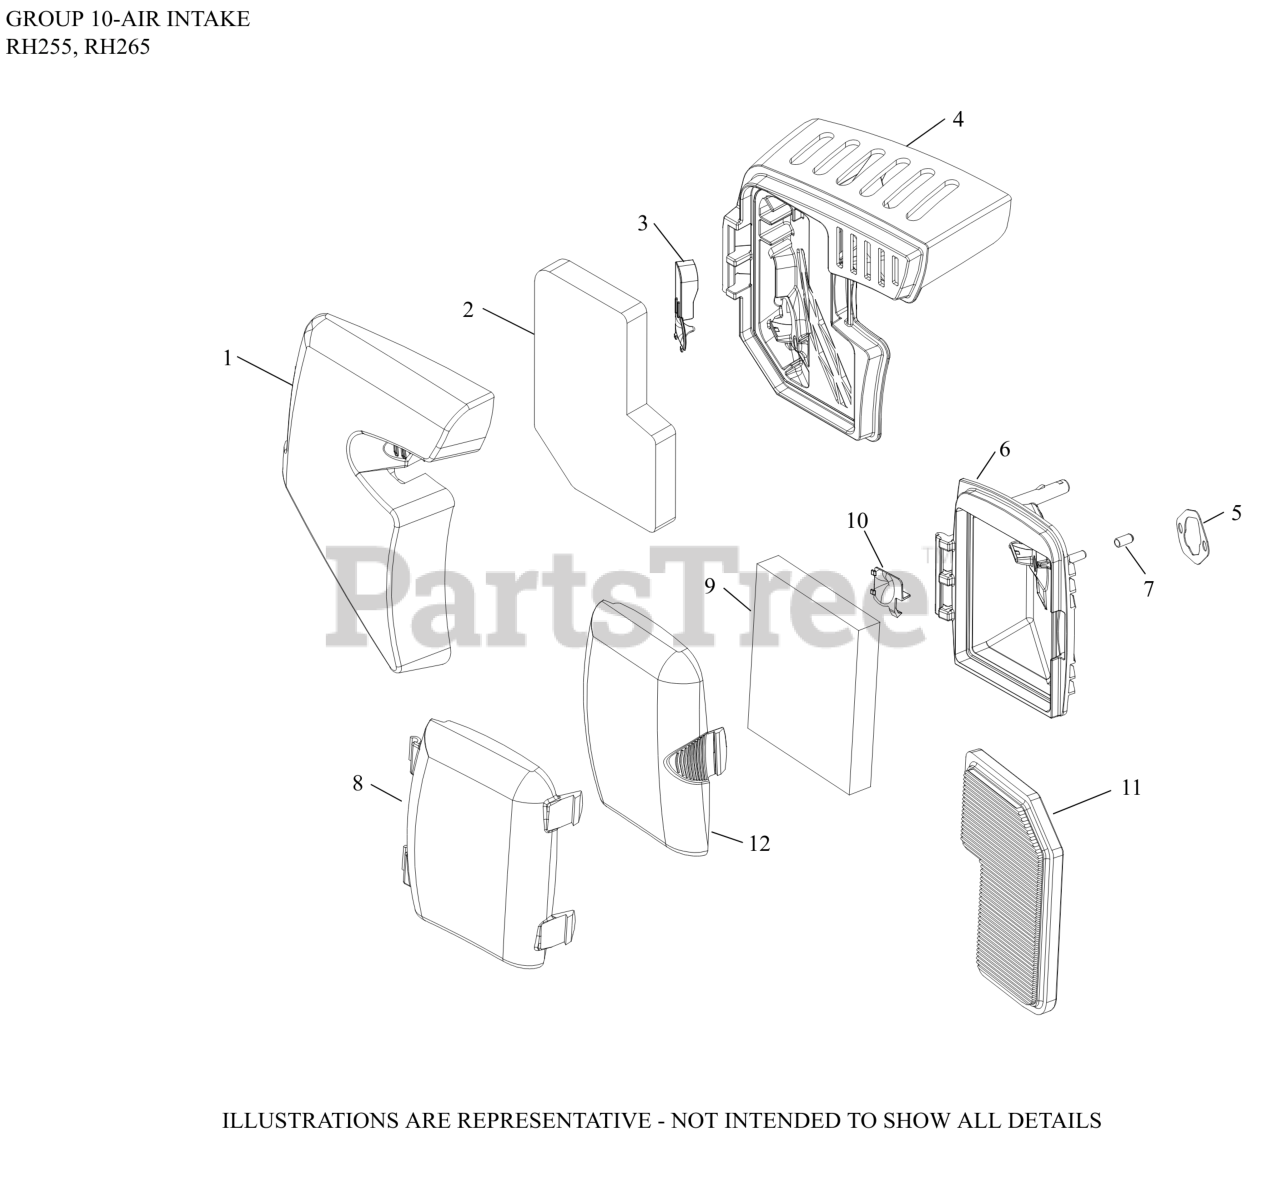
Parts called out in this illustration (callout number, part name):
5	GASKET, CARBURETOR A/C BASE
6	BASE, LOW PROFILE AIR CLEANER (EVAP)
7	CAP, MASKING (CKY)
8	COVER, AIR CLEANER
9	ELEMENT-USE 14 083 15-S
10	CUP, SPIT BACK
